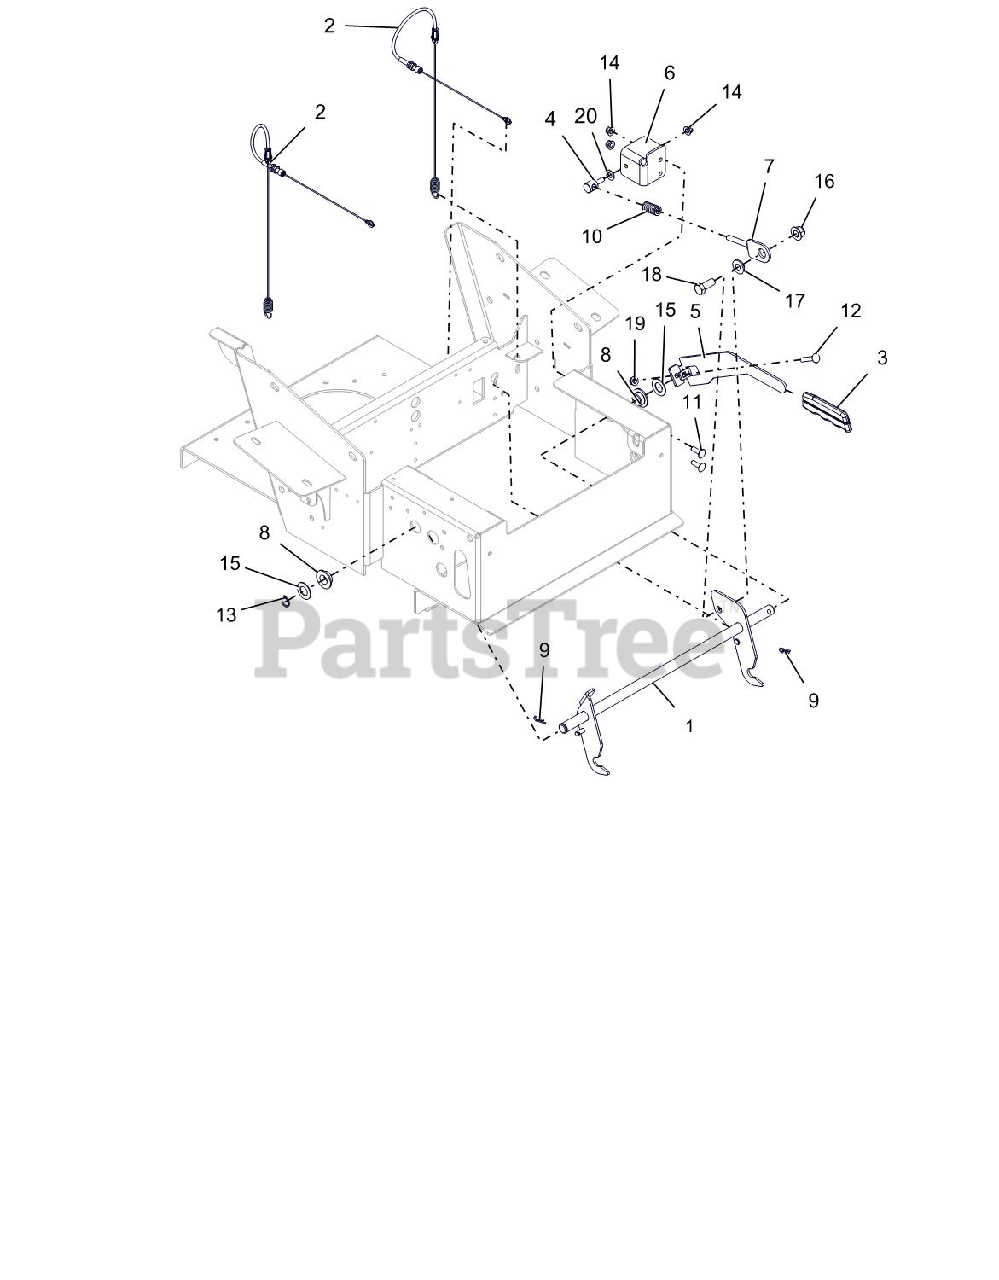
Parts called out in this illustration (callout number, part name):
1	PT/PT100 BRAKE LEVER WMT-LOW F
2	CABLE, BRAKE ACCUATING
3	GRIP, PARKING BRAKE (YELLOW)
4	.38-16 TRUNNION - LOW FILM
5	PT/PT100 BRAKE HANDLE - BLK
6	TRUNNION MTG BRACKET - BLACK
7	WLDMT, BRAKE SPRING MOUNTING
8	BSHG-FLG .762X1.48X.44 NYL
9	PIN-HAIR INT .08X.18X1.18 YWZC
10	SG-COMP .142 X .710 X 1.75
11	@BLT-RDHDSQNK .31-18X1.00 G5YZ
12	@BLT-RDHDSQNK .31-18X1.75 G5YZ
13	RG-RTNG-EXT .689X.078
14	@NUT-LK-NYL-FLG .31-18 YWZC
15	WSHR-FL-STL.755X1.375X.062YWZC
16	@NUT-LK-NYL-FLG .50-13 YWZC
17	BSHG-FLG .515X.750X.310X1.120
18	@BLT-HEX .50-13X1.25 GR5 YWZC
19	@NUT-LK-CTR-FLG .31-18 YZ GR F
20	@WSHR-FL-STL.406X.812X.065 YWZ
